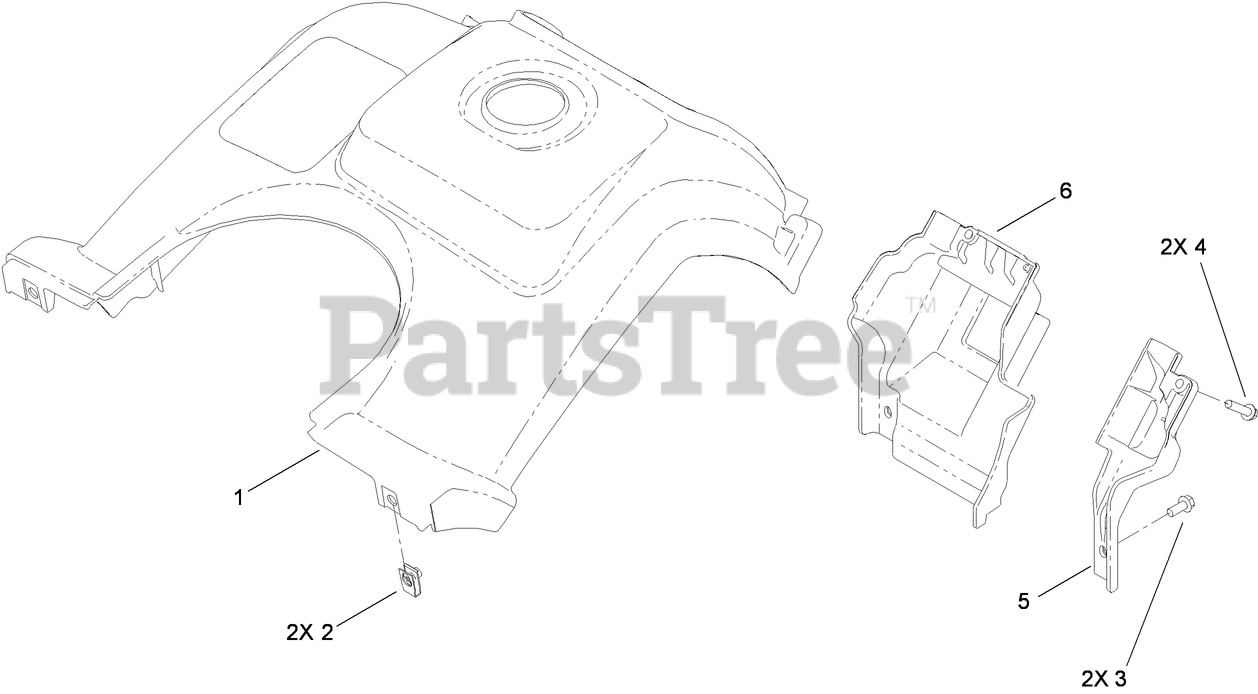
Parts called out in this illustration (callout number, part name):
1	SHROUD ASM
3	SCREW-HWH
4	SCREW-PLASTIC
5	SHROUD-LOWER, LH
6	SHROUD-LOWER, RH
